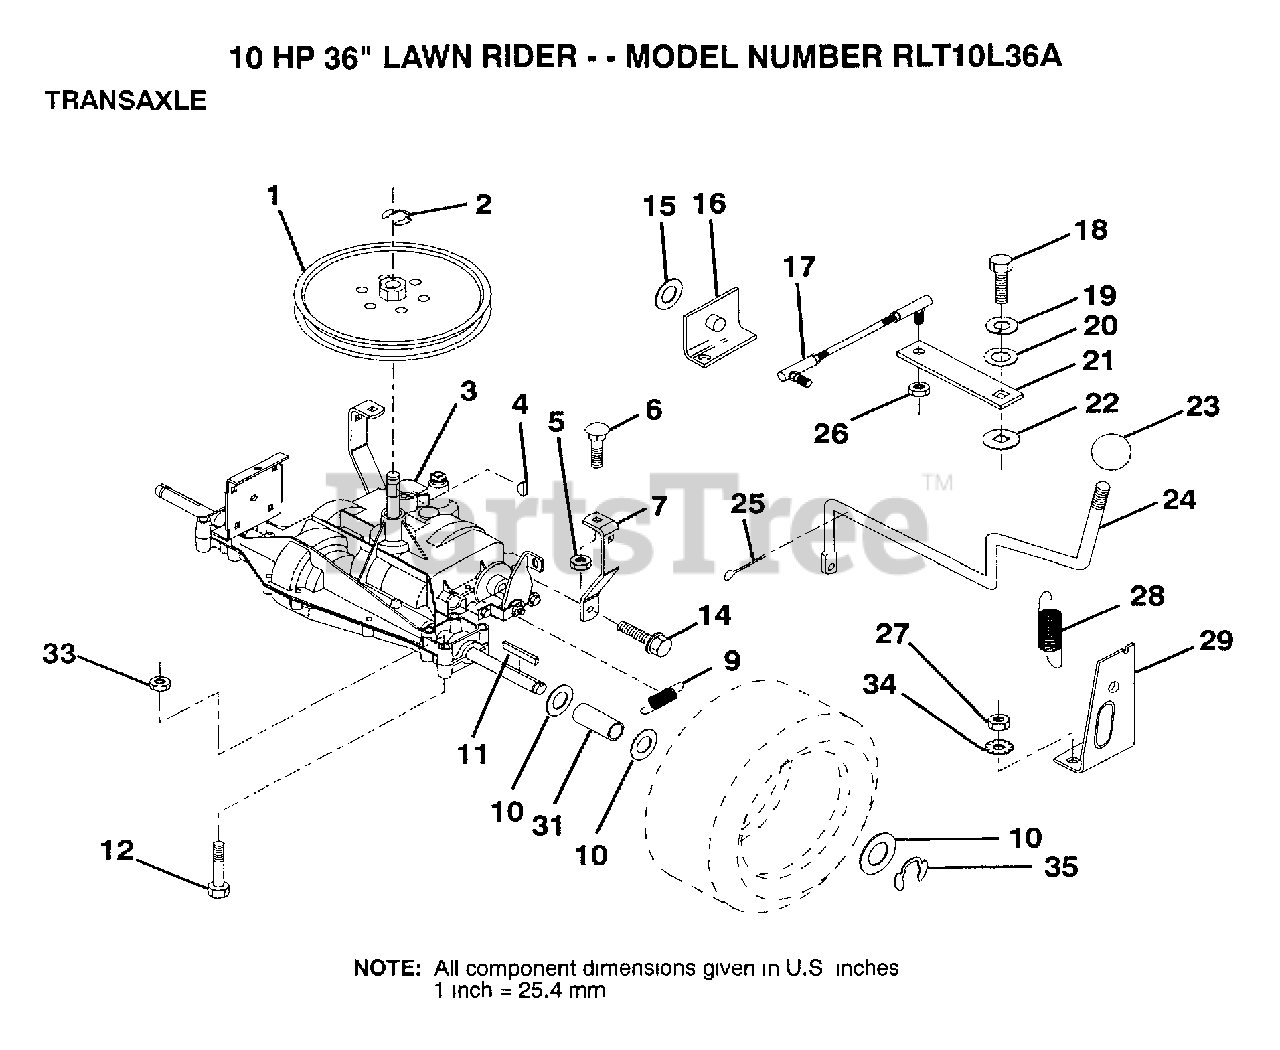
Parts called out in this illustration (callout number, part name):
1	PULLEY
6	BOLT
7	"STRAP,TORQUE"
10	WASHER
11	SQUARE KEY
12	BOLT
14	SCREW
16	"SUPT,HDLE SHT LH"
17	"LINK,SHIFT"
19	LOCKWASHER
20	WASHER LT
21	ARM SHIFT
22	WASH-SHFT PLT LT
23	KNOB T (1/2-HOLE)
24	"ROD,SHIFT"
25	PIN COTTER 1/8
26	NUT.LOCK.5/16-24
28	"SPRING,EXT"
29	"SUPT,HDLE RH"
31	SPACER
34	LOCKWASHER.5/16.E
35	E-RING LT
